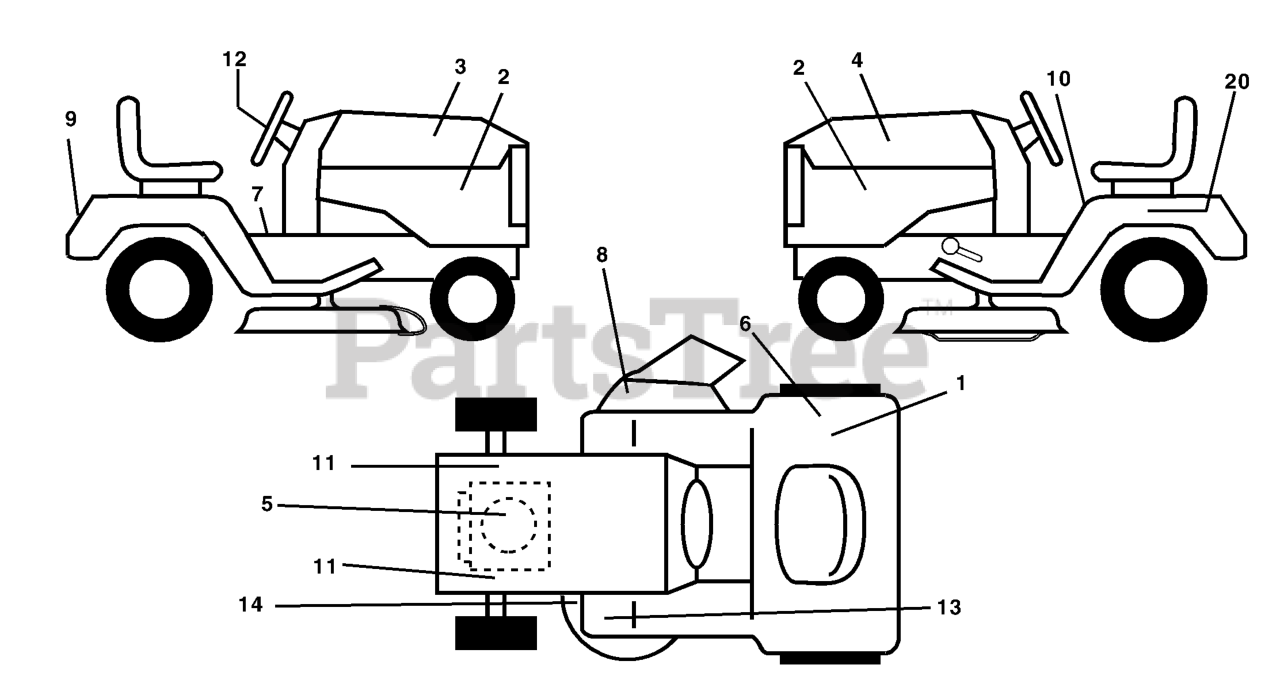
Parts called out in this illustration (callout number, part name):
1	DECAL CERTIFICATION
2	DECAL PNL SIDE
5	DECAL HP ENGINE
6	DECAL EUROPE STANDARD CE
7	DECAL PARK BRAKE
8	DECAL MOWER CUT/FINGER
9	DECAL FENDER HUSQ
10	DECAL READ OWNER'S MAN SYMS
12	DECAL.WHEEL.STEERING.HUSQ.PERM
13	DECAL
14	DECAL V BELT SCHEMATIC
20	DECAL BTRY SYMBOLS
20	DECAL
20	DECAL BY PASS LT HYDRO
